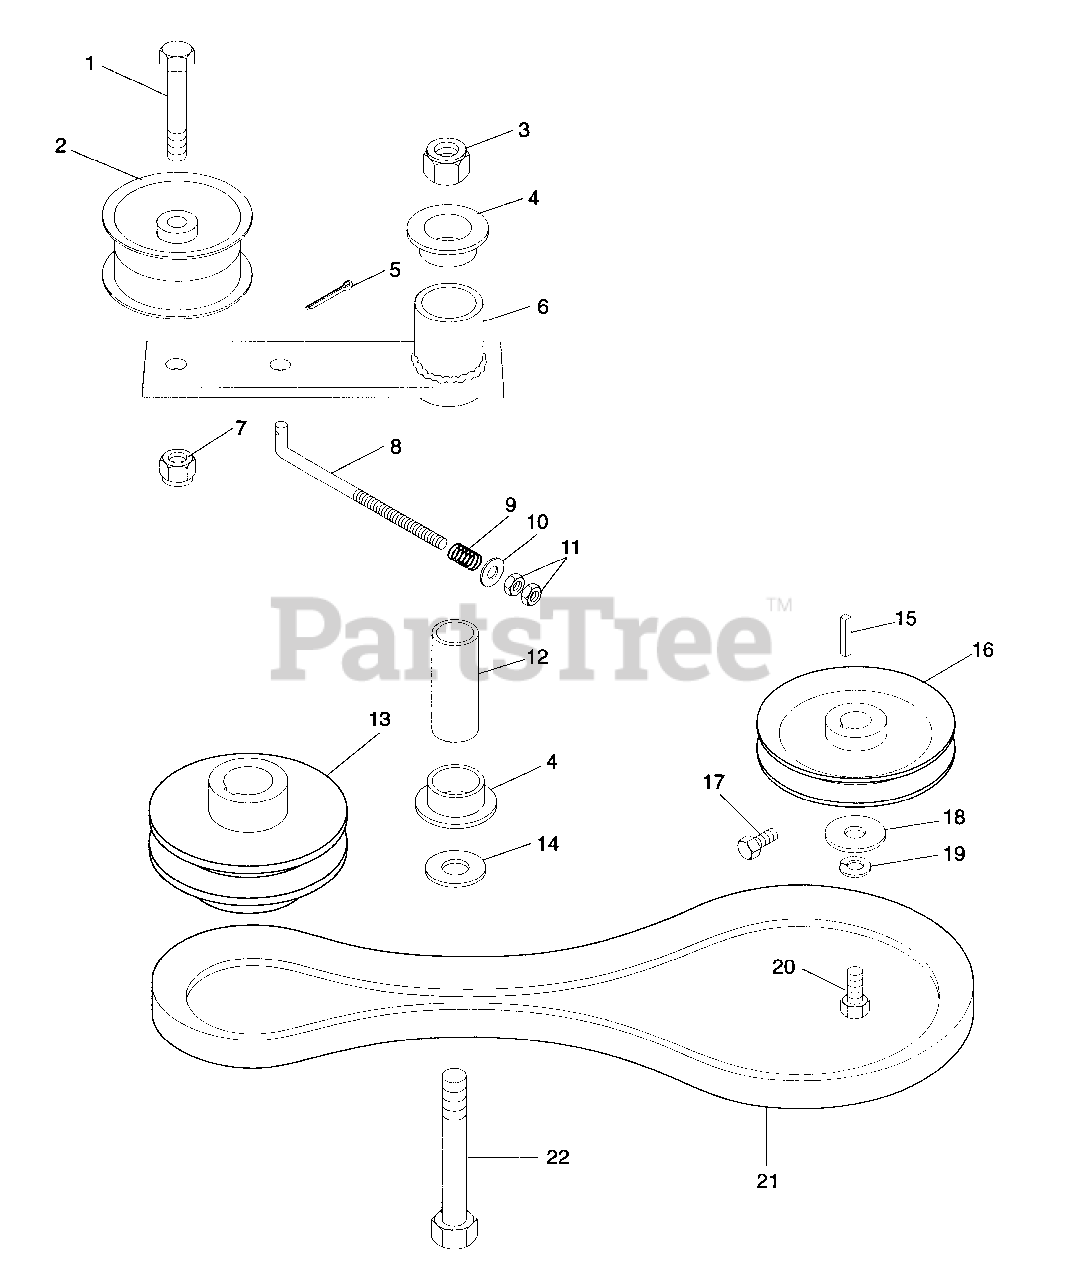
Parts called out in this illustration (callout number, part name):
1	Bolt-Hex .38-16 x 1.75 Grade 5
2	Idler, Pulley, Flat, 3.25 x .625
3	Nut-Locking-Nylon .50-13 Grade 5
4	Bushing-Flange .762 x 1.0 x .580 x 1.48
5	Pin-Cotter .09 x .75
6	Weldment, Ground Drive Idler
7	Nut-Locking-Nylon .375-16 Grade 2
8	Rod, Idler
9	Spring-Compression .125 x .78 x 1.00
10	Washer-Flat-Steel .406 x .812 x .065
11	Nut-Hex .375-24 Grade 2
12	Bushing, Steel, .560 x .745 x 2.04
13	Sheave, Engine Ground Drive
14	Washer-Flat-Steel .531 x 1.062 x .095
15	Key-Straight 5mm x 25mm x 5mm
16	Sheave, 4.0 x .199
17	Bolt-Hex .25-20 x .50 Grade 5
18	Washer-Flat-Steel .281 x 1.250 x .062
19	Washer-Lock .250 Reg.
20	Bolt-Hex M6 x 1.0 x 12mm Lg
21	V-Belt, A-RMA 24.50 x 33/64
22	Bolt-Hex .50-13 x 3.00
